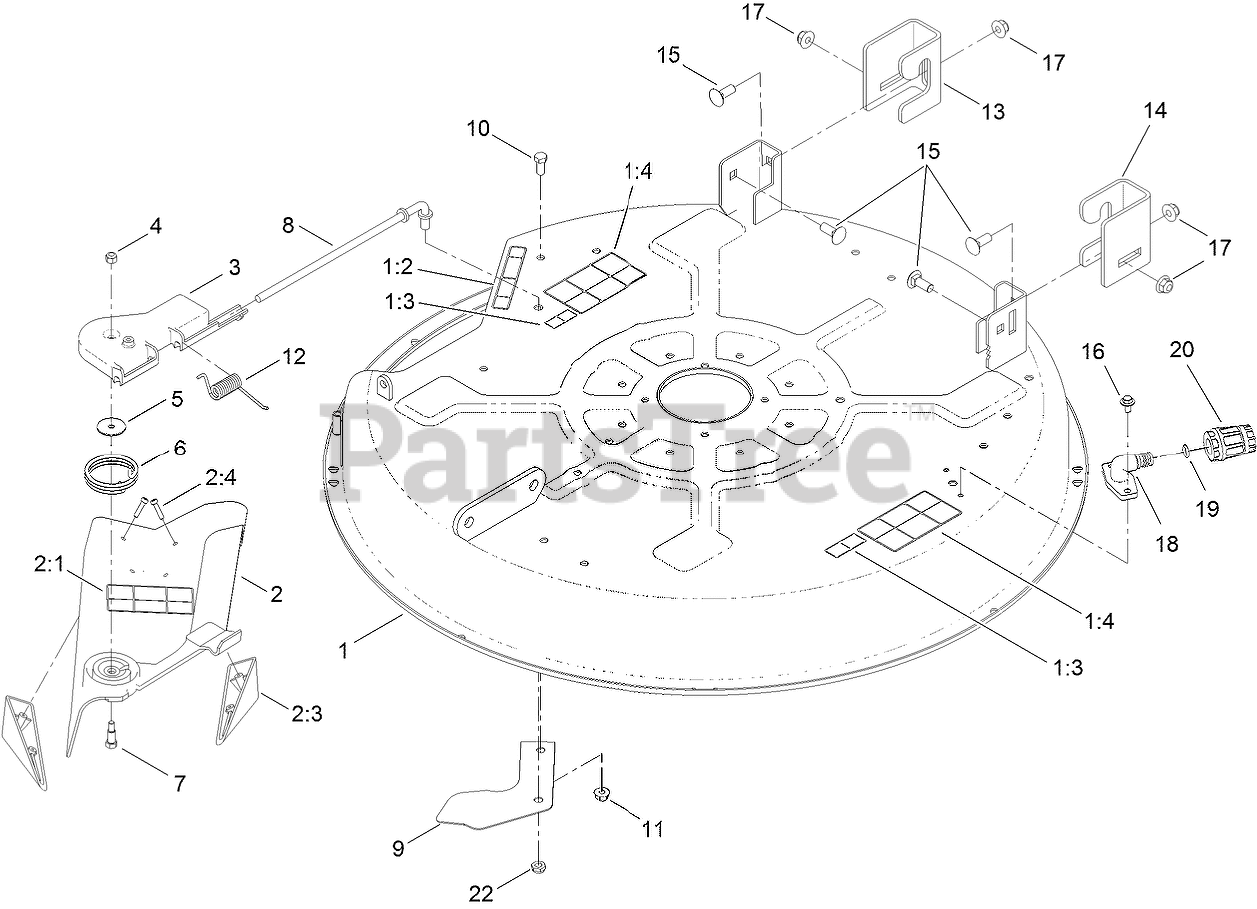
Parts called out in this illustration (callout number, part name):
1	32 INCH DECK AND DECAL ASM
1:2	DECAL-DANGER
1:3	DECAL-DANGER
1:4	DECAL-DANGER
2	32 INCH DEFLECTOR ASM
2:1	DECAL-DANGER
2:3	KICKER
2:4	SCREW-PPH
3	PIVOT-HINGE, DEFLECTOR
4	NUT-LOCK, NI
5	WASHER-FLAT
6	SPRING-TORSION
7	BOLT-SHOULDER
8	ROD-PIVOT
9	RAMP-DEFLECTOR
10	SCREW-HH
11	NUT-HF, NI
12	SPRING-TORSION
13	BRACKET-HANGER, RH
14	BRACKET-HANGER, LH
15	BOLT-CARR
16	SCREW-HHFTF
17	NUT-HF, NI
18	FITTING-WASHOUT
19	O-RING
20	CONNECTOR-HOSE
22	NUT-LOCK, NI
